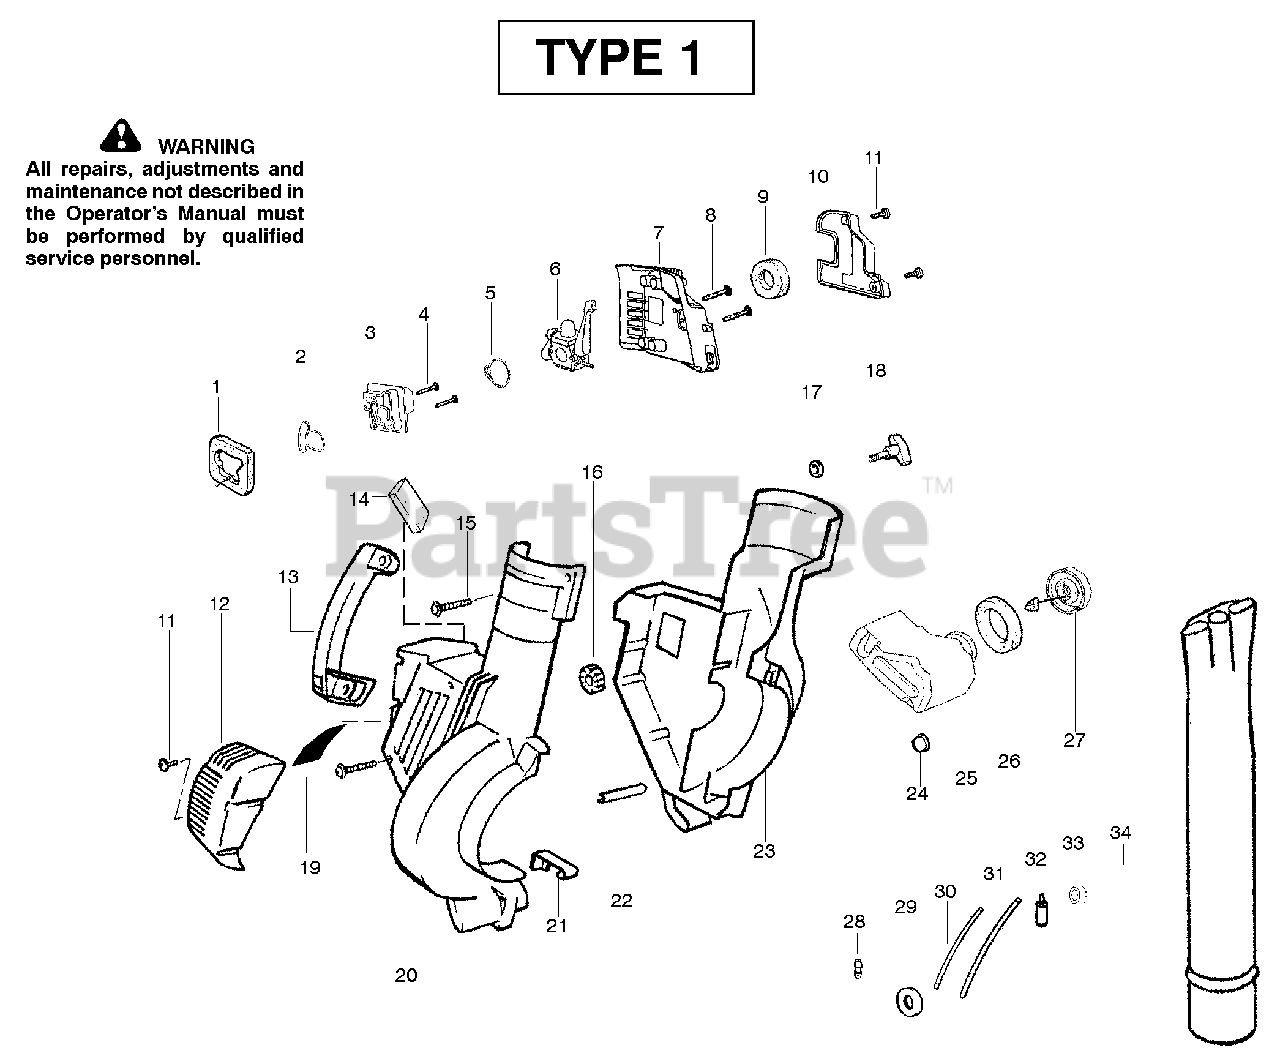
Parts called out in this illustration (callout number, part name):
1	Air Dam (kit)
2	Gasket-Adapter (kit)
3	Carburetor Adaptor
5	Gasket-Carburetor (kit)
6	Kit-Carb Ass'y. Zama-(C1Q-W11C)
6	Kit-Carb Ass'y. Walbro-(WT-606)
8	Screw-Carb.
9	Filter-Air
10	Cover-Air Filter
12	Guard-Muffler
14	Foam - 71.12mm (kit)
16	Isolator
18	Knob-Tube Clamp
19	Reflector-Heat (kit)
20	Shroud-RH
21	Spring-Cover Latch
22	Guide-Starter Rope
23	Shroud - LH
24	Isolator-Crankcase
25	Assy-Fuel Tank
26	Gasket-Fuel Tank
27	Fuel Cap w/Retainer
28	Fitting-Fuel Line
29	Grommet-Shroud
30	Kit-Line Carb/Purge
31	Kit-Line Tank/Purge
32	Assy-Fuel Pick-up
33	Grommet-Fuel line (kit)
34	Tube-Blower
